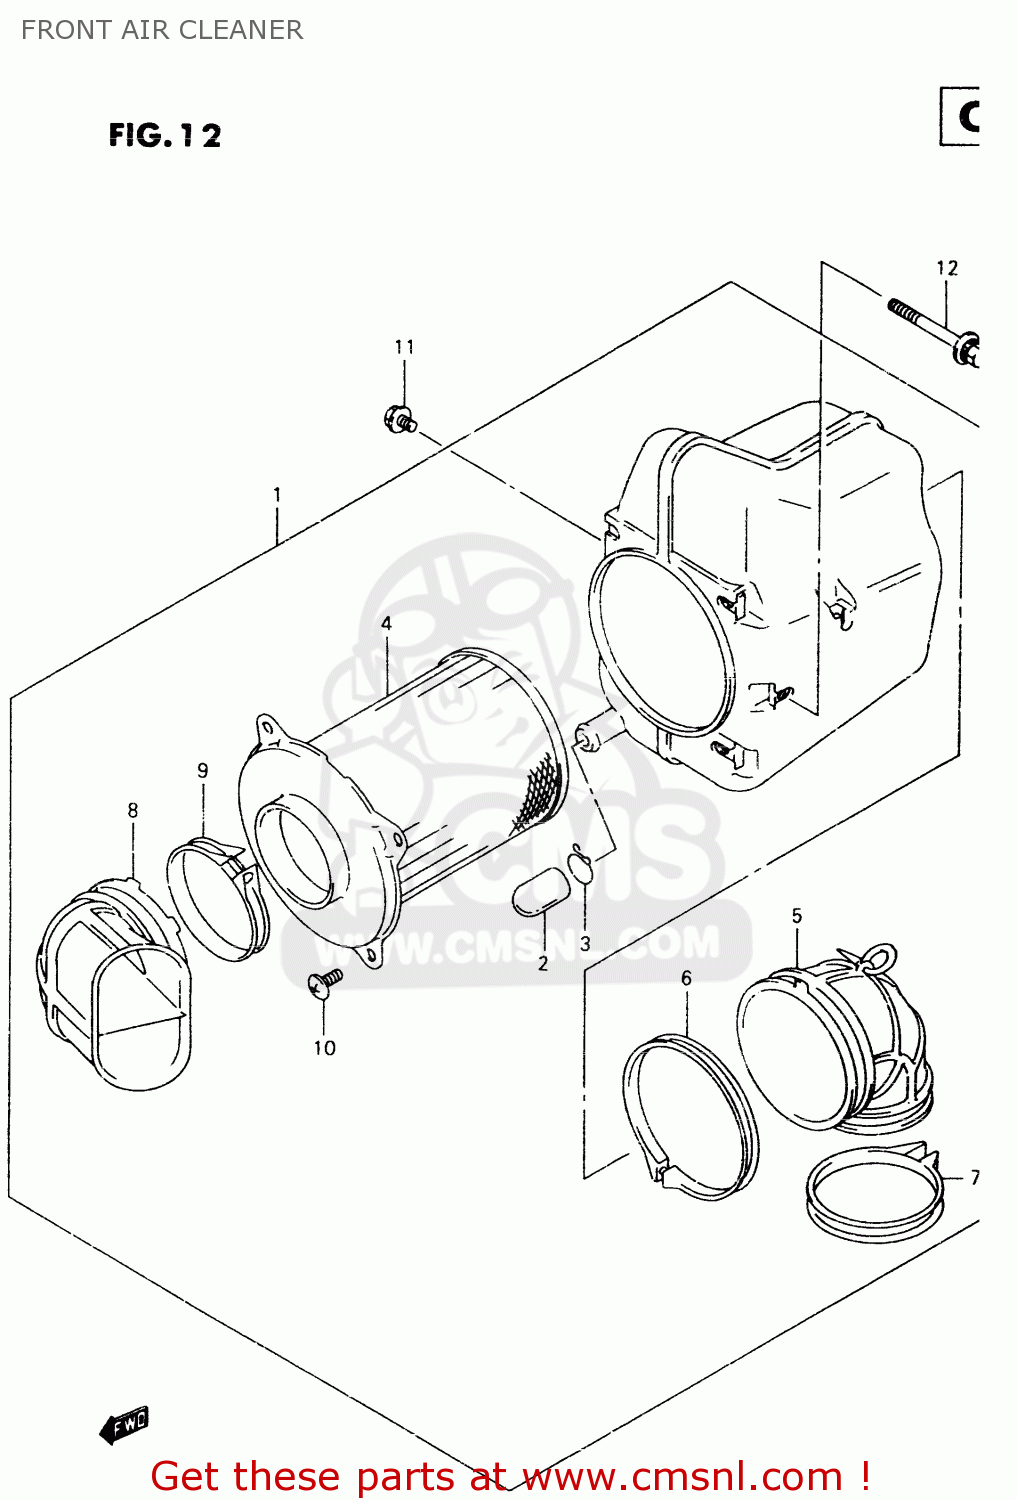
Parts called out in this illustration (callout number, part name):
1	CLEANER ASSY,AIR FR
2	PLUG
3	CLIP
4	FILTER ASSY
5	TUBE,AIR CLEANER OUTLET
6	CLAMP
7	CLAMP
8	TUBE,INLET
9	CLAMP
10	SCREW
11	BOLT
12	BOLT
